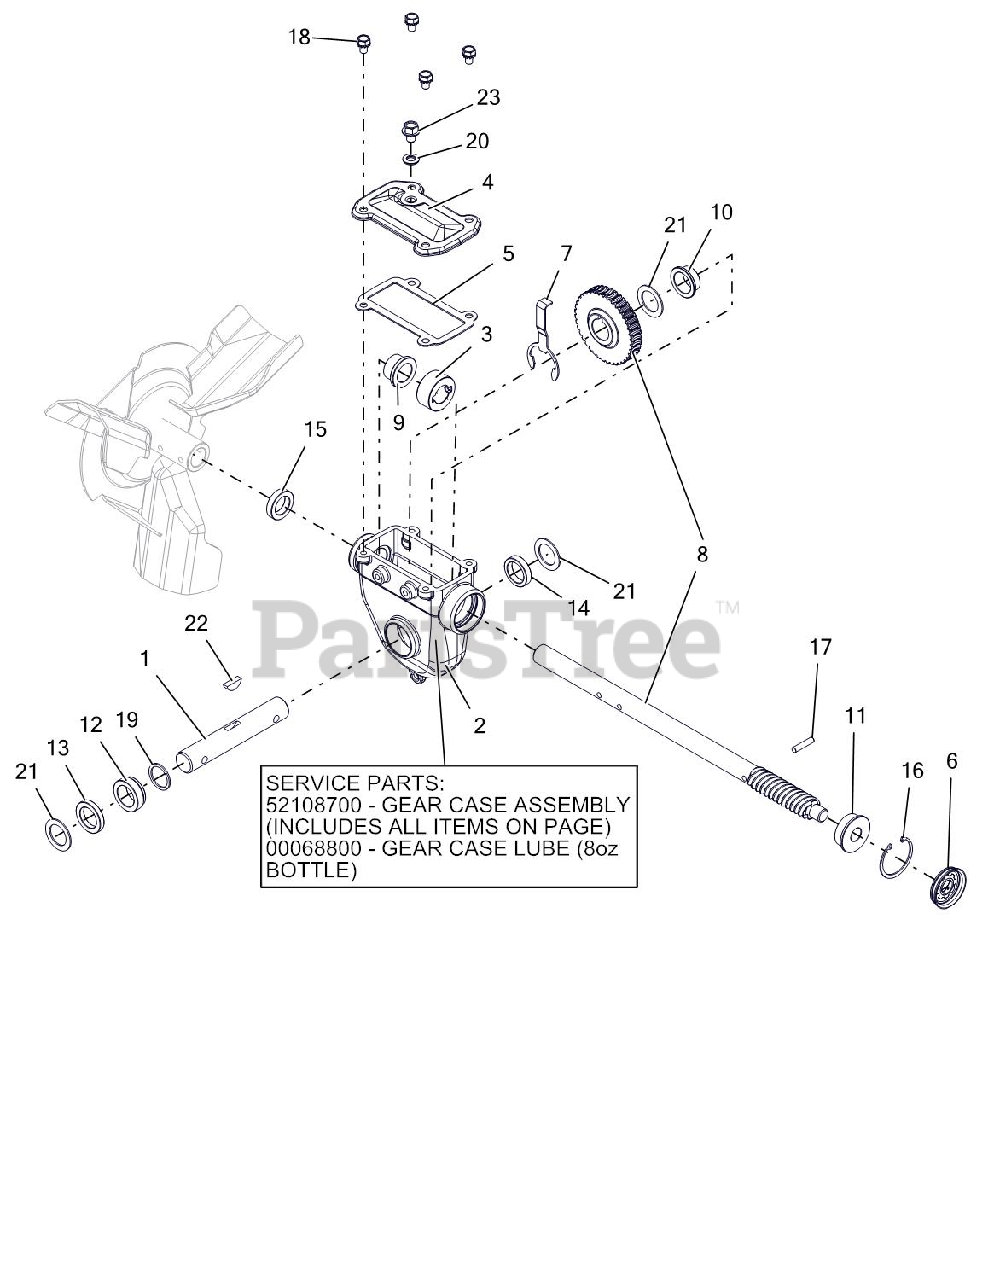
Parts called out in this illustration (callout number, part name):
1	RAKE SHAFT, SHORT-COMMON
2	ARIENS L3 LUBE, 8 OZ BOTTLE
2	GEARCASE, LARGE MACHINED
2	KIT, SERVICE - DLX GEAR CASE
3	THRUST COLLAR, .875"ID SLIPFIT
4	COVER, TOP - LARGE IRON
5	GASKET, TOP - LARGE GEARCASE
6	COVER, GEAR CASE 1.75"
7	BUSHING RETAINER, LARGE
8	KIT, SERVICE-WORM SHAFT & GEAR
9	BSHG-FLG .879X1.128X.75X1.45
10	BSHG-FLG 1.006X1.128X.555X1.45
11	BSHG-FLG .628X1.503X.58X1.725
12	BSHG-FLG LARGE, RIGHT
13	SEAL-OIL .999X1.500X.250 TBC29
14	SEAL-OIL .999X1.375X.312 TBC29
15	SEAL-OIL .873X1.375X.312 TBC29
16	RG-RTNG-INT 1.750X.062
17	PIN-STR .250X1.12 6150
18	BOLT, SEMS .31-18X.50 GR5 YWZC
19	WSHR-FL-STL 1.010X1.250X.068YZ
20	WSHR-BND-SEAL .38X.75X.11 GALV
21	WSHR-FL-STL 1.010X1.505X.062YZ
22	KEY-WDRF .25X.875 HRD #A
23	@SCR-ROLOK .38-16X.50 HWH YWZC
